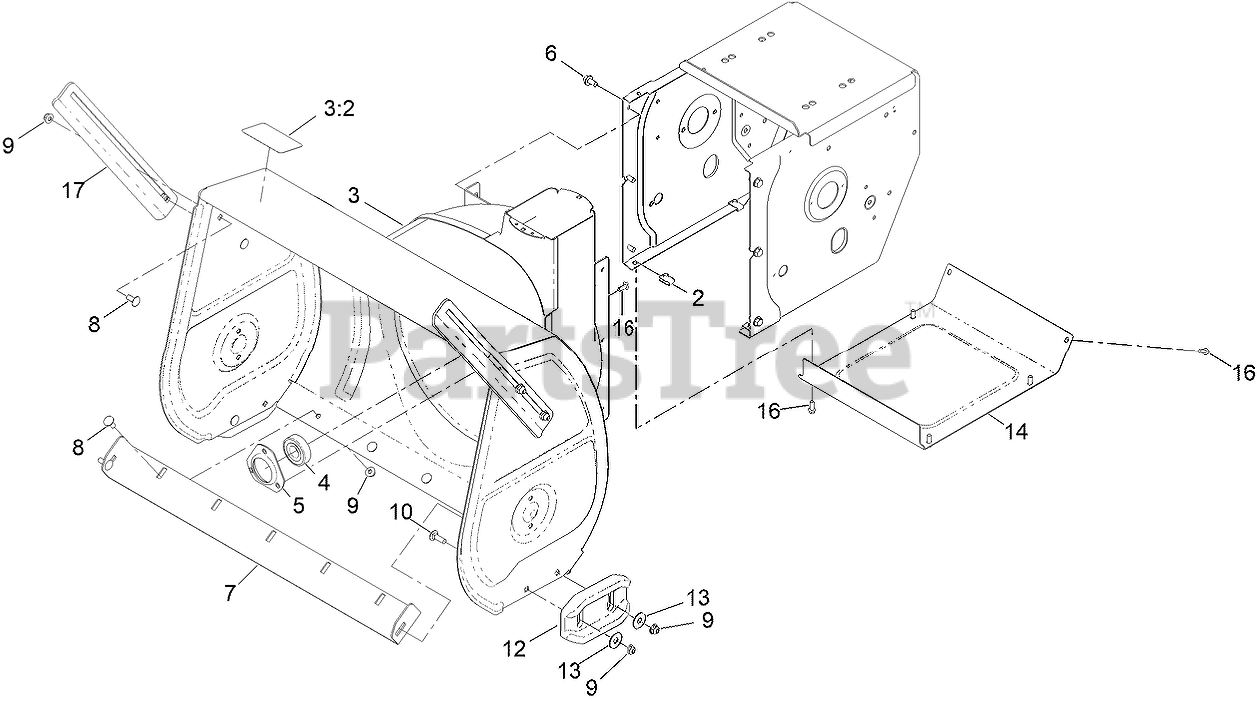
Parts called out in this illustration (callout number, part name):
3	AUGER HOUSING ASM
3:2	DECAL-DANGER, AUGER
4	BEARING-BALL
5	RETAINER-BEARING
6	SCREW-HWHTF
7	BLADE-SCRAPER
8	BOLT-CARR
9	NUT-HF
10	BOLT-CARR
12	SKID-CAST
13	WASHER-FLAT
14	COVER-BOTTOM
16	SCREW-HWH
17	BREAKER-DRIFT, SIDE
